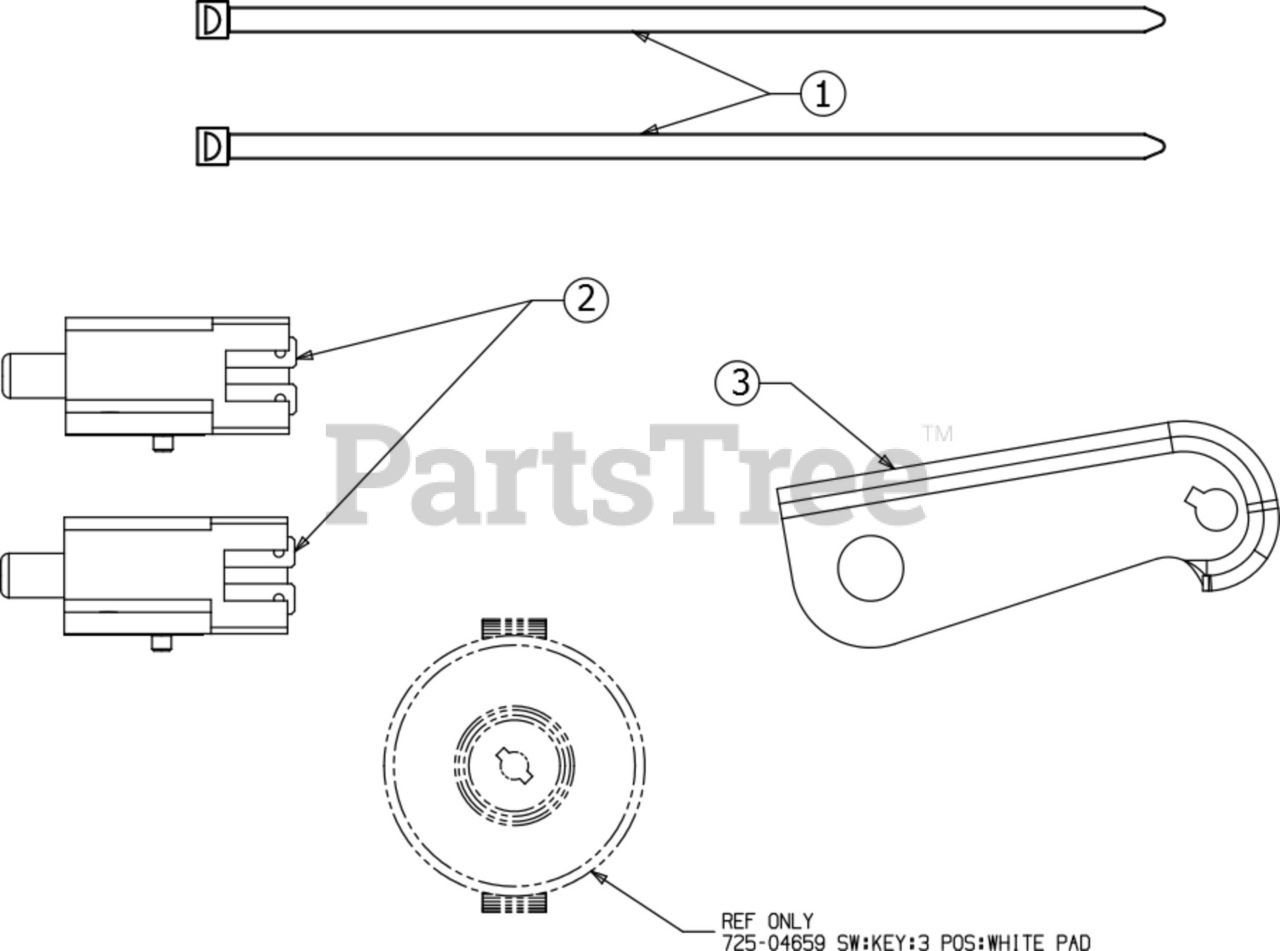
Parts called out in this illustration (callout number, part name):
1	CABLE TIE 7"
2	INTERLOCK SWITCH (NO/NC)
3	LATCH SPEED BRACKET
